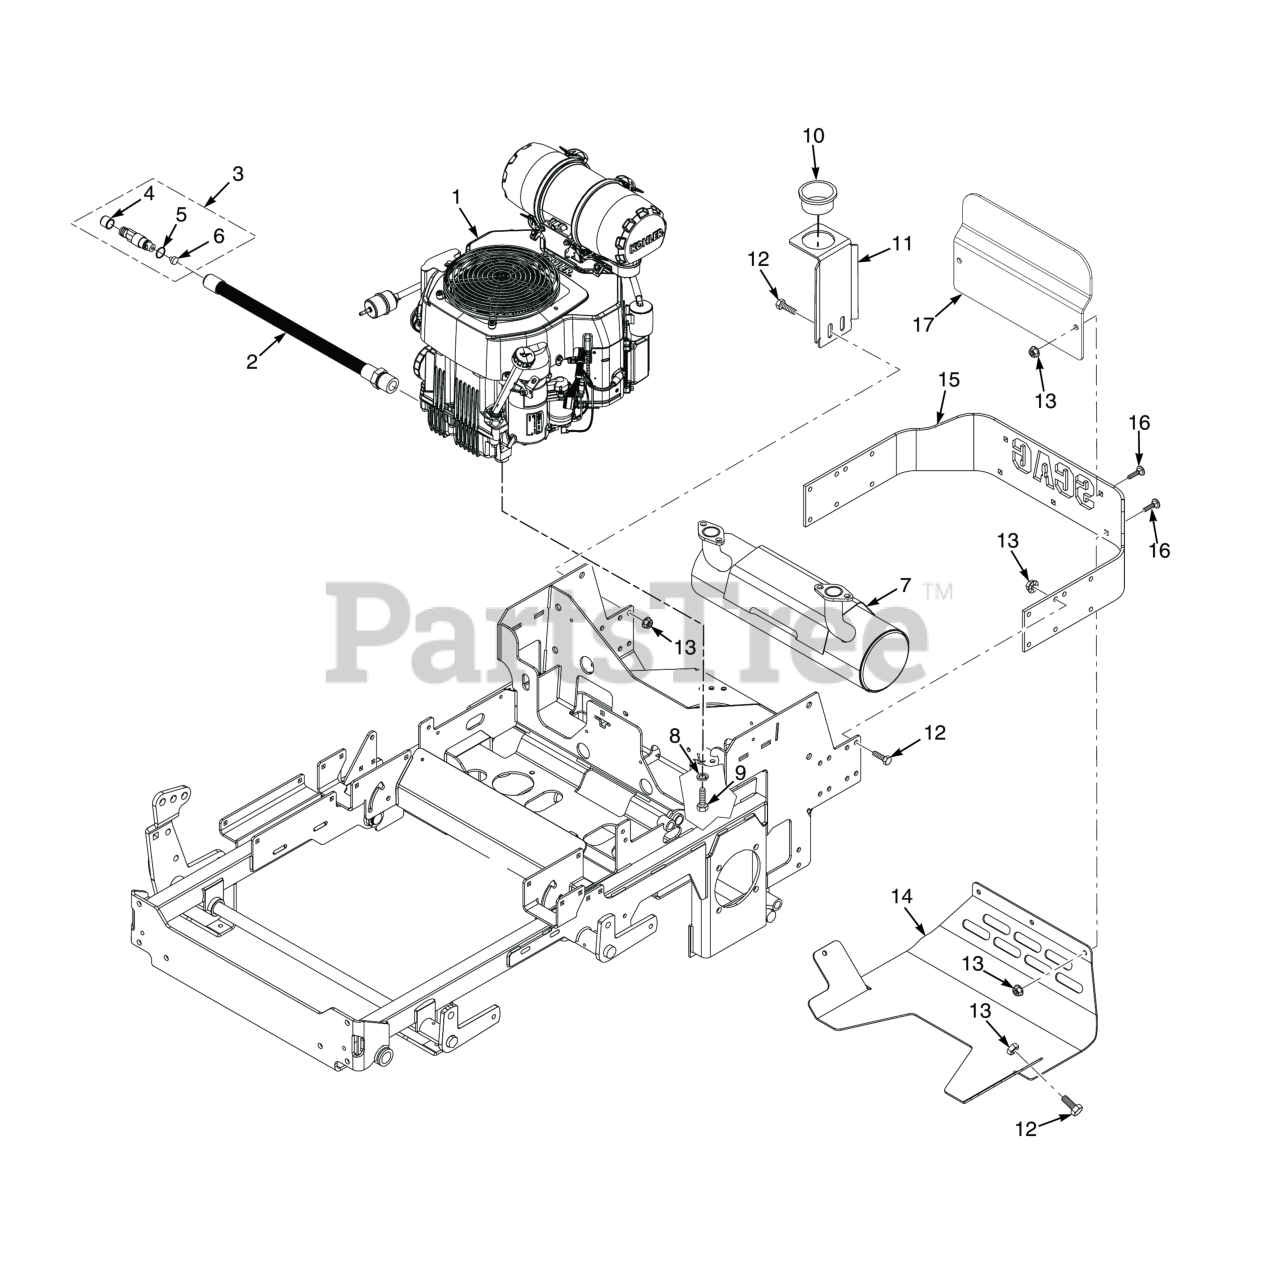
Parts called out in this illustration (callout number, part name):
2	Hose Assembly, Engine Oil Drain - Kawasaki FS/FX
3	Valve Assembly, Oil Drain
4	O-Ring
5	O-Ring
7	Muffler, Kawasaki 22 & 23FX, 24FT & FT-EFI
8	Lockwasher, 3/8" Spring, Kawasaki FX / FT & FT-EFI / B&S 32BV
9	Bolt, Hex Head 3/8-16 x 1-1/4", Kawasaki FX / FT & FT-EFI
10	Bushing, Thick Panel Snap
11	Bracket, Oil Drain Hose
12	Bolt, Hex Head, 3/8-16 x 1 Gr. 5
13	NUT, 3/8-16 SERRATED FLANGE HEX HEAD
14	Plate, Skid
15	Bumper, Rear
16	Carriage Bolt, 3/8-16 x 1.0"
17	Guard, Engine
